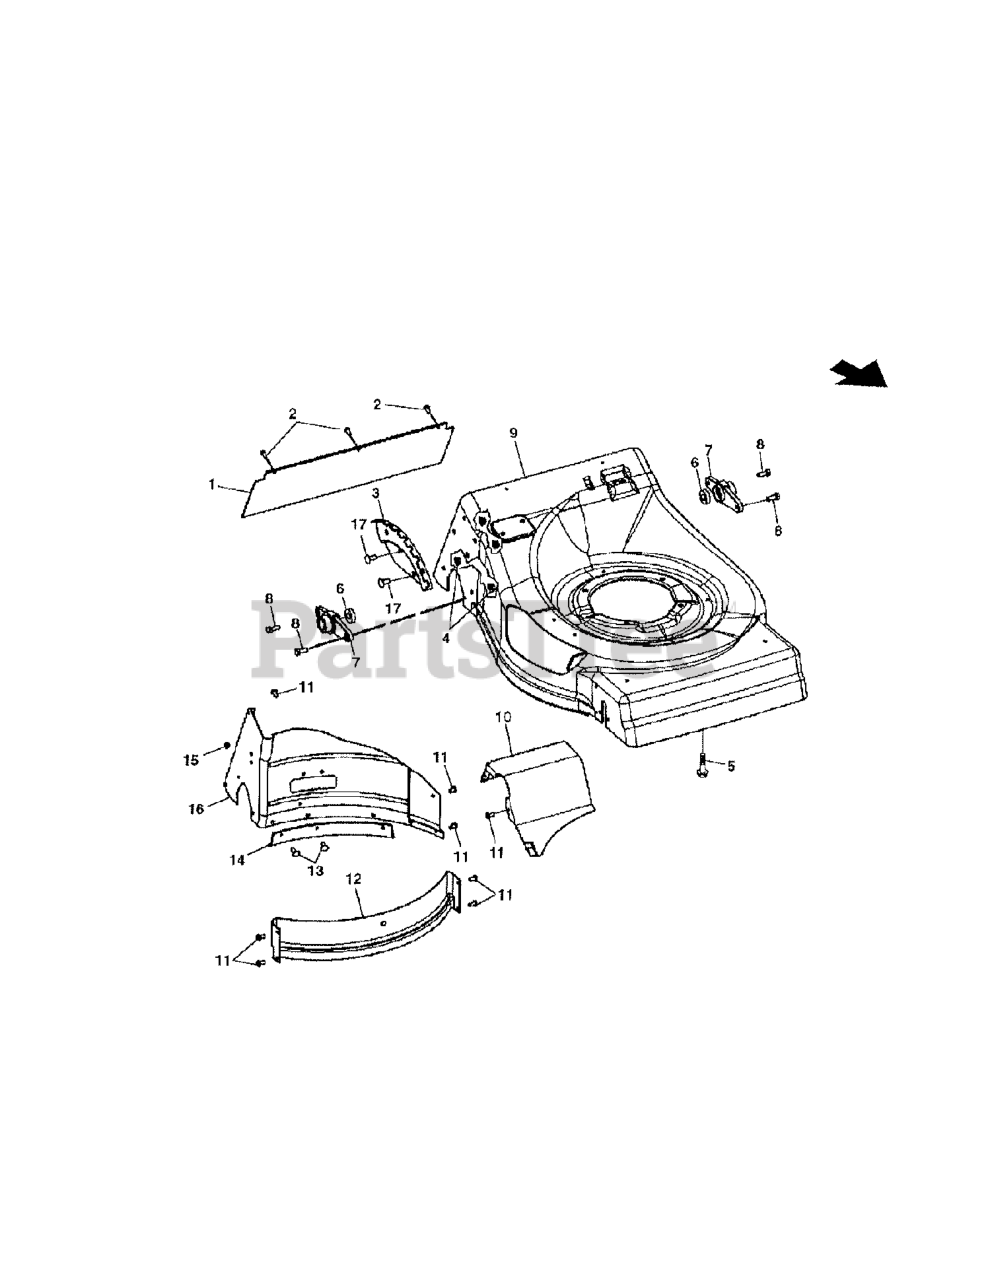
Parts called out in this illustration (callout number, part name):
1	DEFLECTOR, REAR, 21" WBM, RD
2	HWST,10-24X.50 SEMS
3	PLATE, HOC INDEX, 21" WBM, RD
4	FLN, 5/16-18 YZ
5	HWST, 3/8-16 X 1
6	BEARING, BALL, AXLE
7	BEARING HOLDER, 21" WBM, RD
8	HHCS, 5/16 X 3/4 GR5 YZ
9	DECK, 21" RD
10	BAFFLE, RIGHT REAR, 21" WBM, RD
11	TORX ST, 1/4-20 X .550
12	BAFFLE, FRONT 21" WBM, RD
13	FHSNB 10-24X1/2
14	BAFFLE, EXTENSION, 21" RD WBM
15	HLN, 10-24 UNC-2B W/NYLON INSERT
16	BAFFLE, LEFT REAR, 21"RD,WBM
17	RHSSNB, 5/16-18 X 3/4 GR5 YZ
